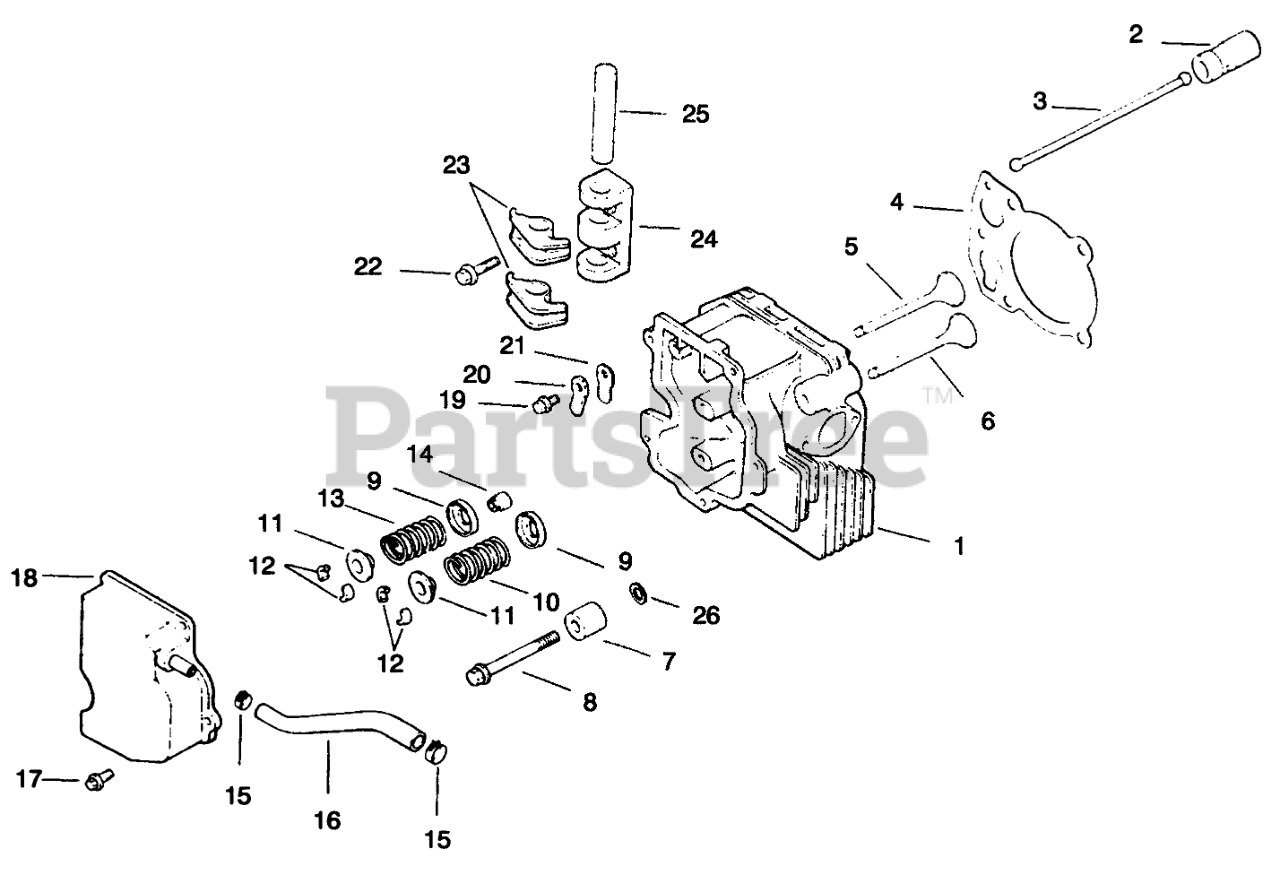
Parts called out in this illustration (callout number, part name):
1	Cylinder Head
2	Lifter-Valve
3	Rod-Push
4	Gasket-Cylinder Head
5	Valve-Intake STD
6	Valve-Exhaust STD
7	Spacer-Head Bolt
8	Screw M10x1.5x80
9	Retainer-Spring
10	Spring-Valve
11	Cap-Spring, Valve
12	Retainer Kit
13	Spring-Valve, Exhaust
14	Seal-Valve Stem
15	Clamp
16	Hose-Breather
17	Screw
18	Cover-Valve w/Nipple
19	Screw
20	Retainer-Reed
21	Reed-Breather
22	Screw
23	Arm-Rocker
24	Bridge-Rocker Arm
25	Shaft-Rocker Arm
26	Washer
